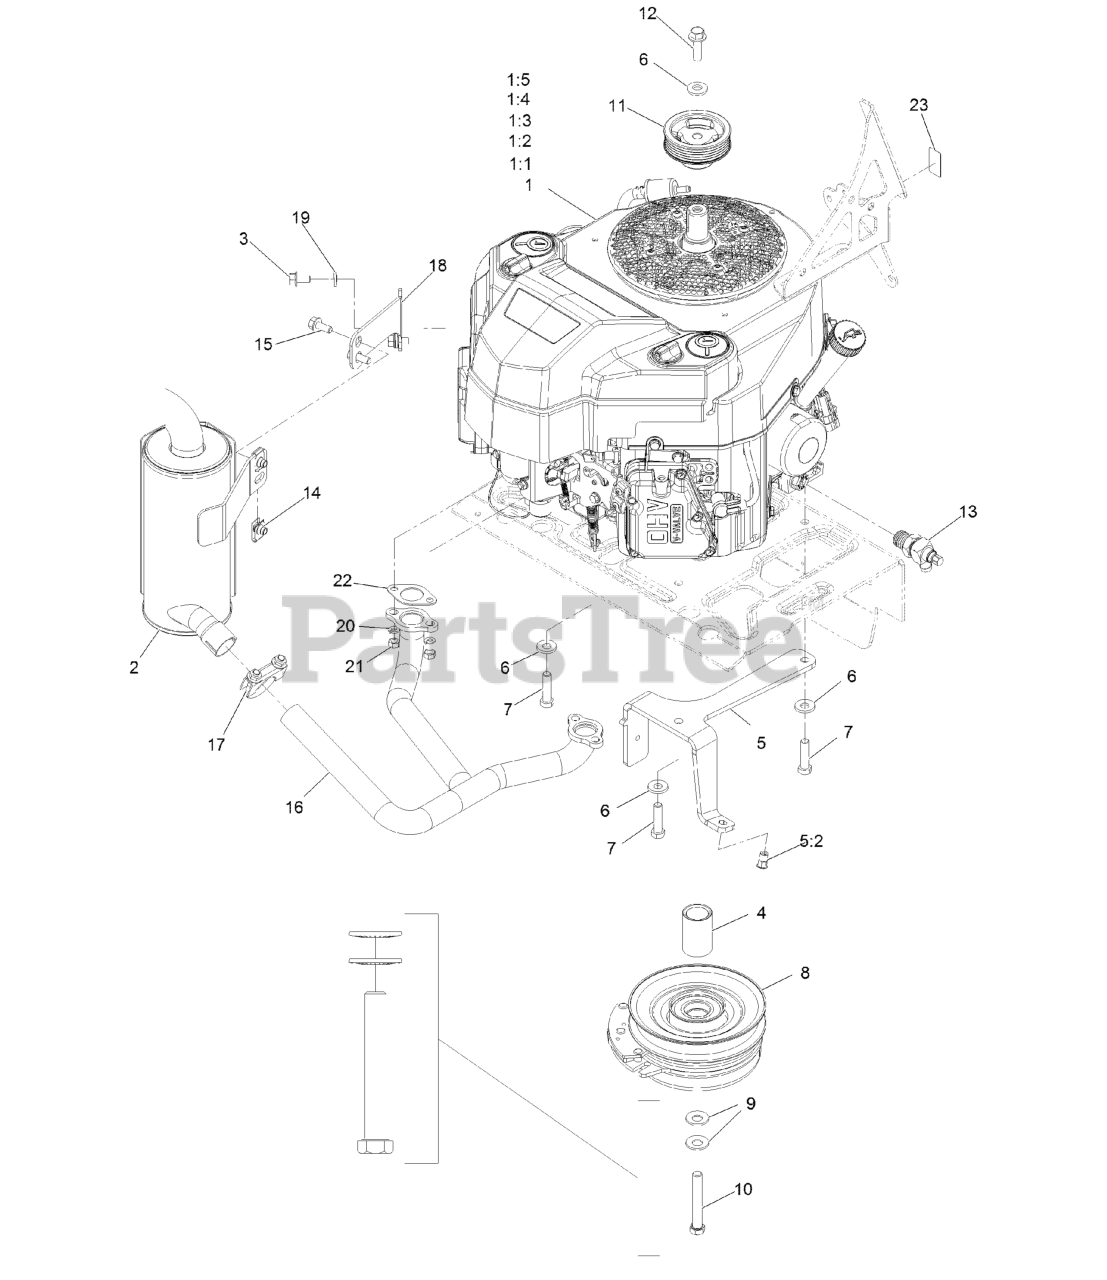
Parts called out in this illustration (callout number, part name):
1:1	Kawasaki 49065-7007Engine Oil Filter
1:2	Kawasaki 49019-0027 Fuel Filter
1:4	Kawasaki 11013-7046 Foam Pre-Filter
1:5	Kawasaki 11013-0752 Air Filter
2	MUFFLER-VERTICAL KA
3	SCREW-HHF
4	SPACER-CLUTCH
5	ASM-CLUTCH ANCHOR W/INSERT
5:2	NUT-CLINCH,HEX
6	WASHER-BELLEVILLE
7	SCREW-HH
8	CLUTCH 105
9	WASHER-SPRING
10	SCREW-HH W/LOCTITE
11	PULLEY, CRANK
12	SCREW-HHF
13	DRAIN-OIL VALVE
15	SCREW-HHF
16	CLAMP-MUFFLER
17	WASHER-LOCK
18	BRACKET-MUFFLER VERTICAL
19	WASHER-LOCK
20	WASHER-LOCK
22	GASKET-EXHAUST
23	DECAL-10W-50 OIL
